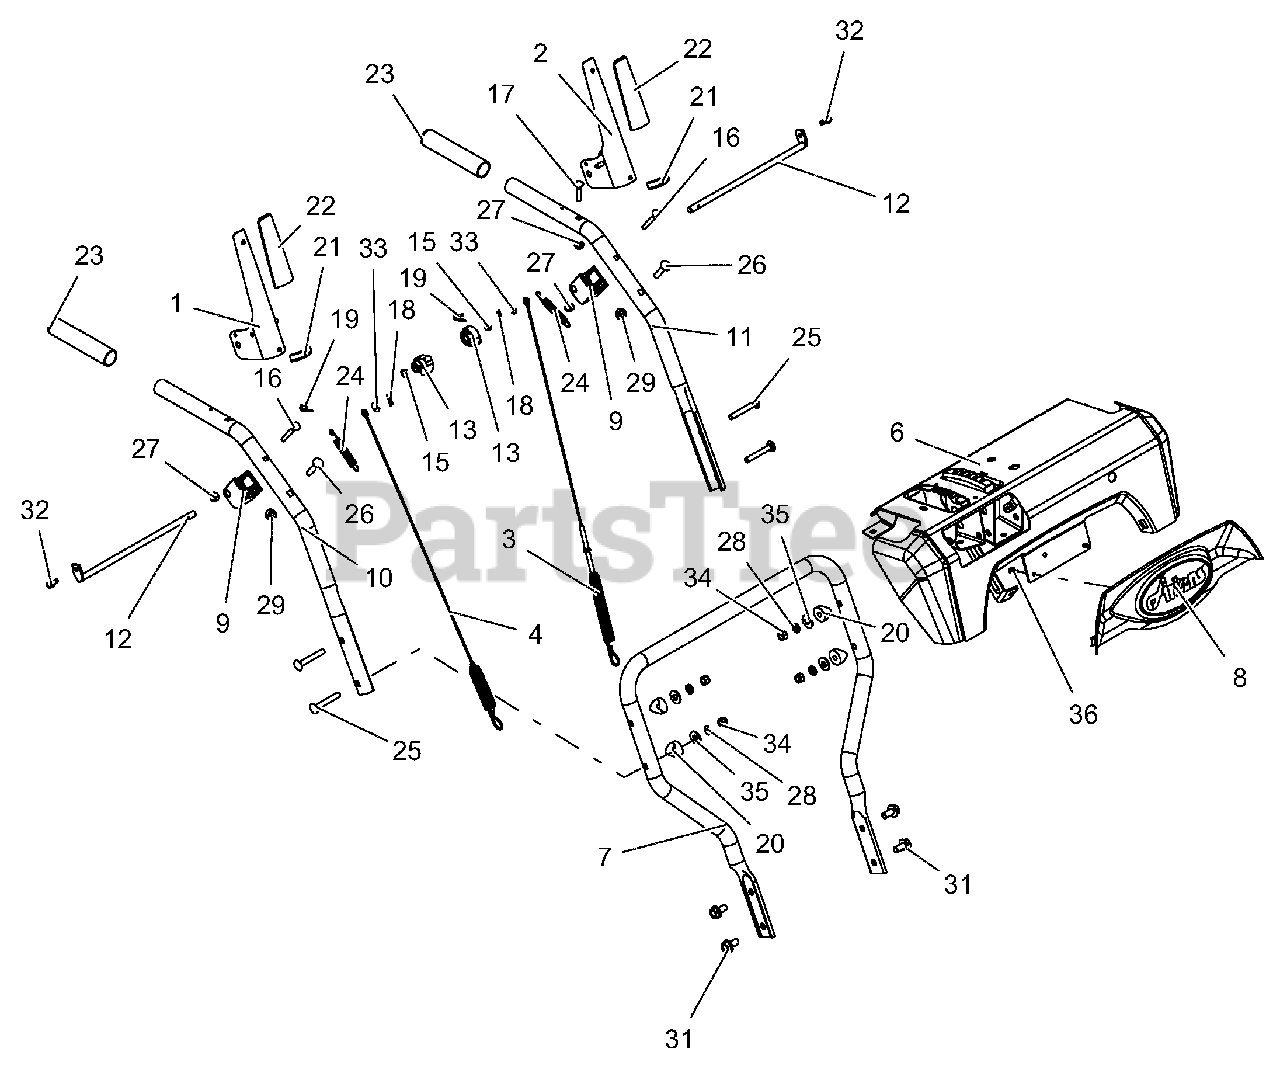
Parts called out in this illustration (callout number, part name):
1	LEVER, CLUTCH-RH
2	LEVER, CLUTCH-LH
3	CABLE, UPPER TRACTION
4	CABLE, AUGER (DELUXE & PRO)
6	CTRL PANEL W/DECAL, CRNK TRACK
7	HANDLEBAR, LOWER - DELUXE
8	DASH BEZEL, ARIENS LOGO - PRO
9	BLOCK, CLUTCH PADDLE
10	HANDLEBAR, UPPER - RH
11	HANDLEBAR, UPPER - LH
12	ROD, PADDLE MOUNT - PRO
13	CAM, INTERLOCK
15	BUSHING, POLYLINER-.38 SNAPIN
16	BLT-RDHDXLSQNK .25-20X2.0 G5YZ
17	BLT-RDHDXLSQNK.25-20X1.25 G5ZC
18	PIN-HAIR INT .06X.18X.77
19	PIN, SPRING CLIP
20	SPACER, HANDLEBAR
21	EDGING, CLUTCH PADDLE - 2.00"
22	CLUTCH PADDLE SLEEVE - GRAY
23	HANDLE GRIP
24	SPRING, EXTENSION
25	@BLT-RDHDSQNK .31-18X2.25 G5YZ
26	@BLT-RDHDSQNK .31-18X1.50 G5YZ
27	@NUT-LK-CTR-FLG .25-20 YWZC
28	WSHR-LK .312X.097 HVY YWZC
29	@NUT-LK-TOP-FLG .31-18 YWZC
31	BLT-SERHFWH .38-16X.75 YWZC
32	SCR-TAP .25-20X.50 HWH TR YWZ
33	@WSHR-FL-STL.281X.62X.065 YWZC
34	@NUT-LK-NYL .312-18 YWZC
35	@WSHR-FL-STL.38X.875X.083 YWZC
36	SCR-TAP #10X.50 BOSS INDHXHD
